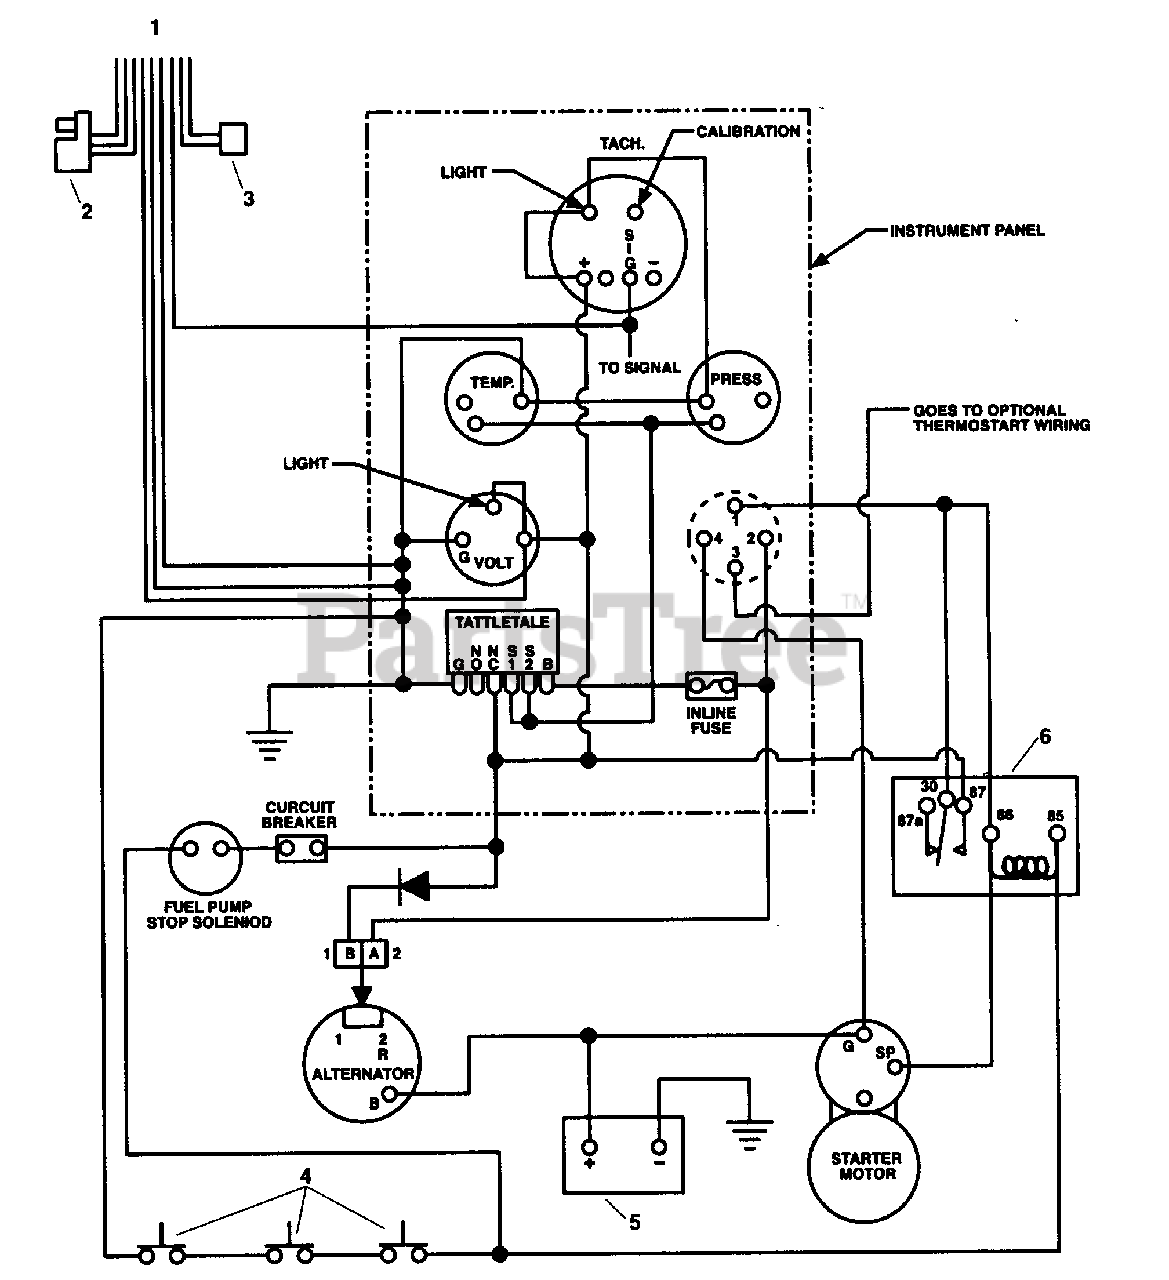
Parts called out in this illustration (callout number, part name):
1	Module-Load Control
2	Pre-Set Switch Assembly
3	Valve-Hydraulic
4	Safety Switch
6	Relay
